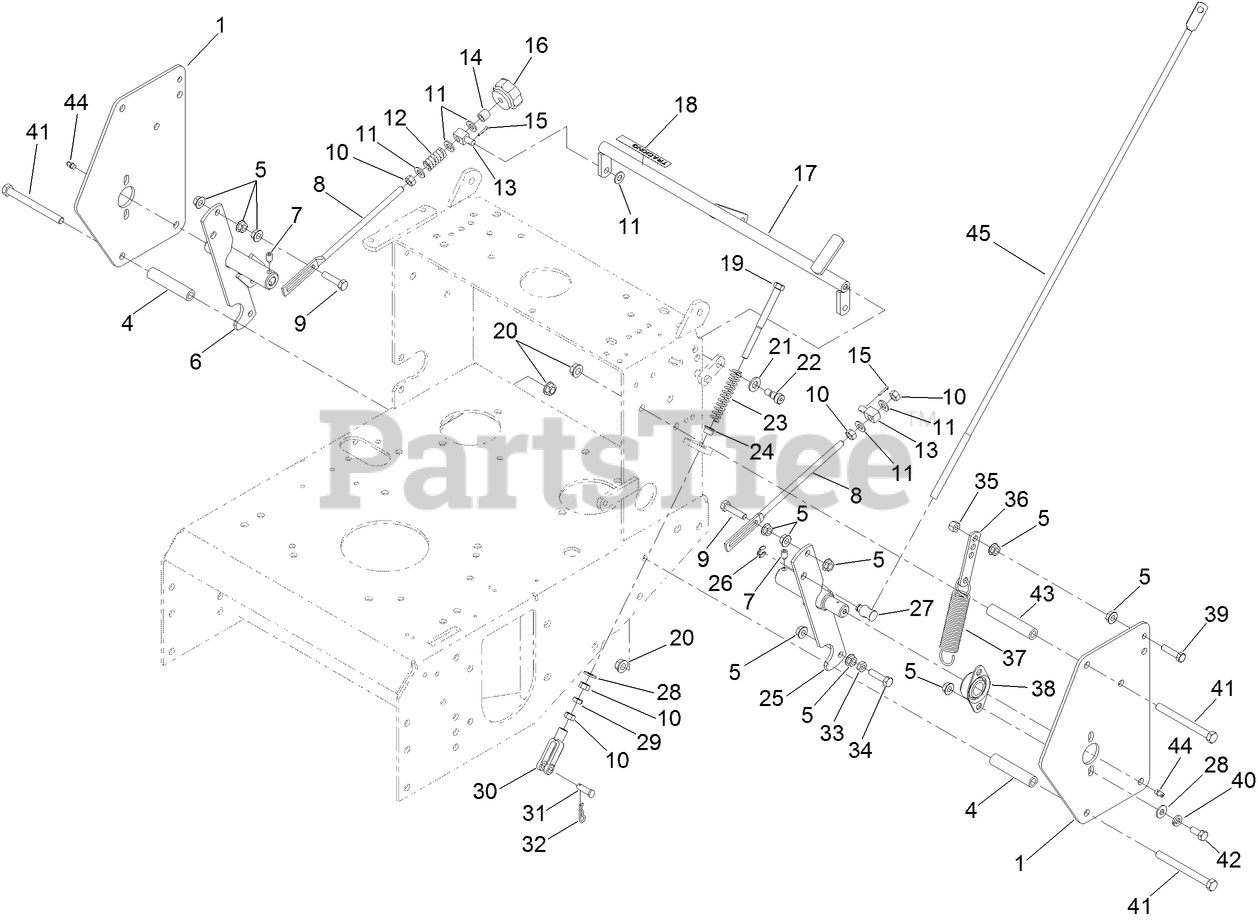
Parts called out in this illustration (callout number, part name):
1	SHIELD-CONTROL
4	SPACER-SHIELD
5	NUT-HF
6	SHAFT-CONTROL, RH
7	SCREW-SET
8	LINK-CONTROL, SPEED
9	SCREW-HH
10	NUT-HEX
11	WASHER-PLAIN
12	SPRING-COMPRESSION
13	SWIVEL-ADJUSTABLE, SHORT
14	SPACER
15	PIN-COTTER
16	KNOB-TRACKING
17	Crank-Control, Speed
18	DECAL-TRACKING
19	BOLT-RETURN, NEUTRAL
20	NUT-HHF, WHIZ
21	WASHER-FLAT
22	SCREW-HSH
23	SPRING-RETURN, NEUTRAL
24	BUSHING-FLANGED
25	Shaft-Control, LH
26	RING-RETAINING
27	SWIVEL-LEVER, DRIVE
28	WASHER-FLAT
29	NUT-JAM
30	YOKE-ADJUSTABLE
31	PIN-CLEVIS
32	PIN-COTTER
33	NUT-JAM
34	SCREW-HH, SPECIAL
35	NUT-LOCK, NI
36	TAB-SPRING, EXTENSION
37	SPRING-EXTENSION
38	BEARING-FLANGE, SIDE
39	BOLT-TAP, HH
40	WASHER-LOCK
41	SCREW-HH
42	SCREW-HH
43	Spacer-Shield
44	FITTING-GREASE
45	ROD-LEVER, DRIVE
